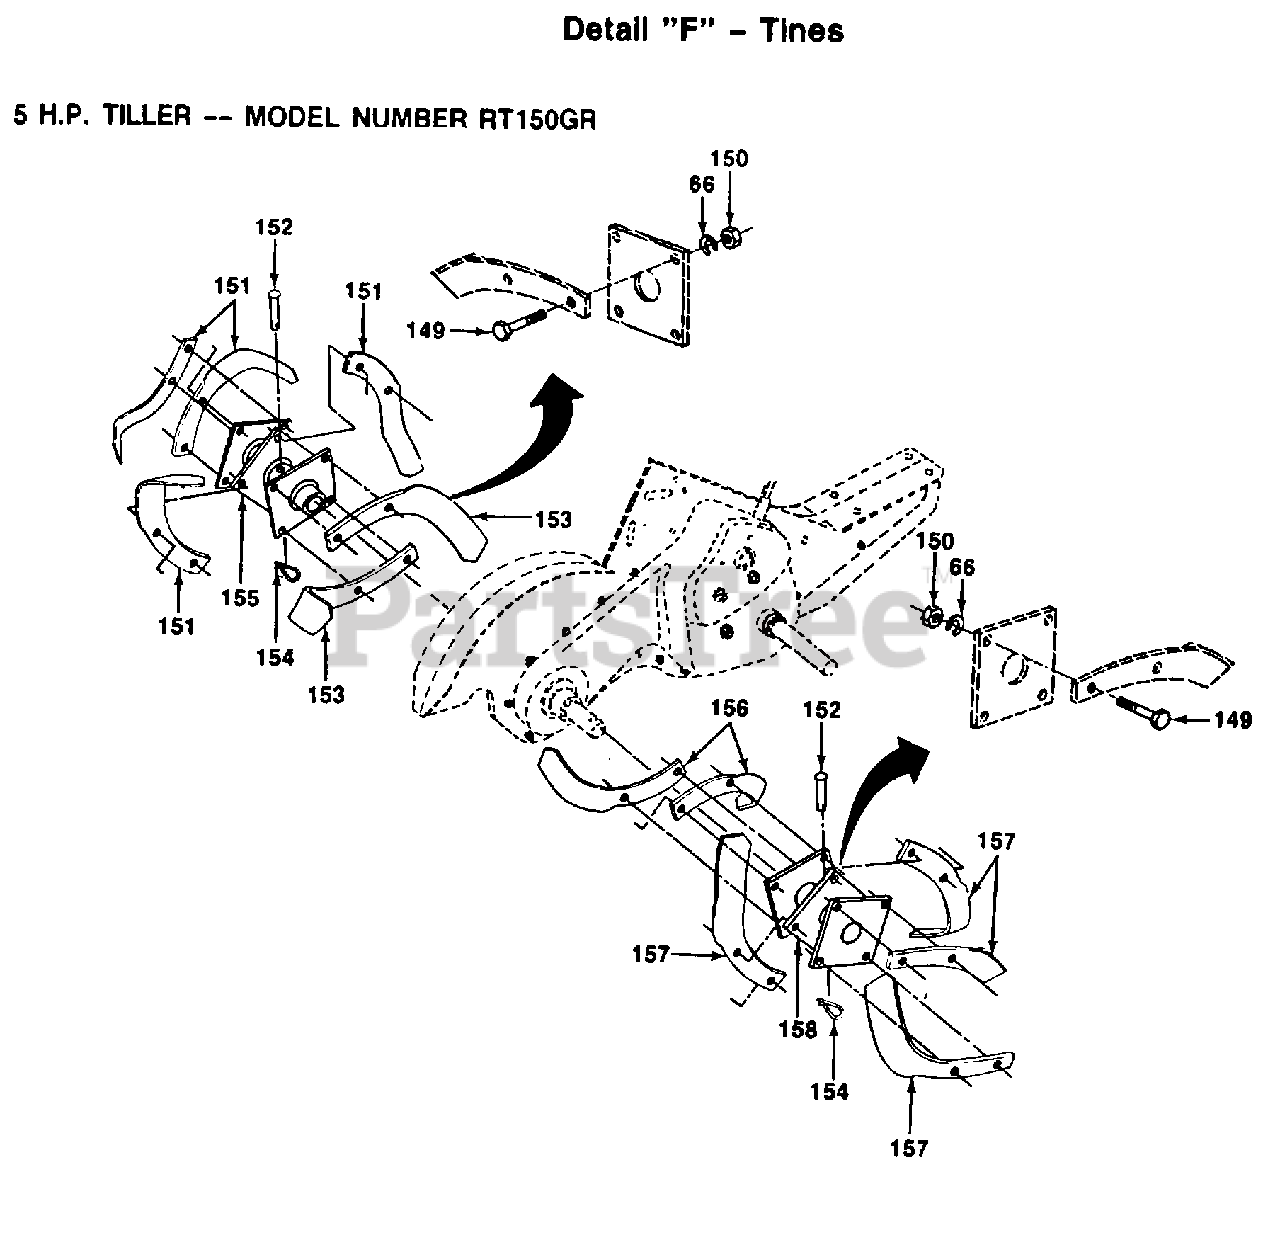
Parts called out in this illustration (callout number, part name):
66	LOCKWASHER
149	BOLT
152	RIVET.PAN HD.1.75
153	"TINE.LH.12"""
154	RETAINER.SPRING
155	TINE ASSY LH CRT
156	"TINE.RH.12"""
158	TINE ASSY RH CRT
